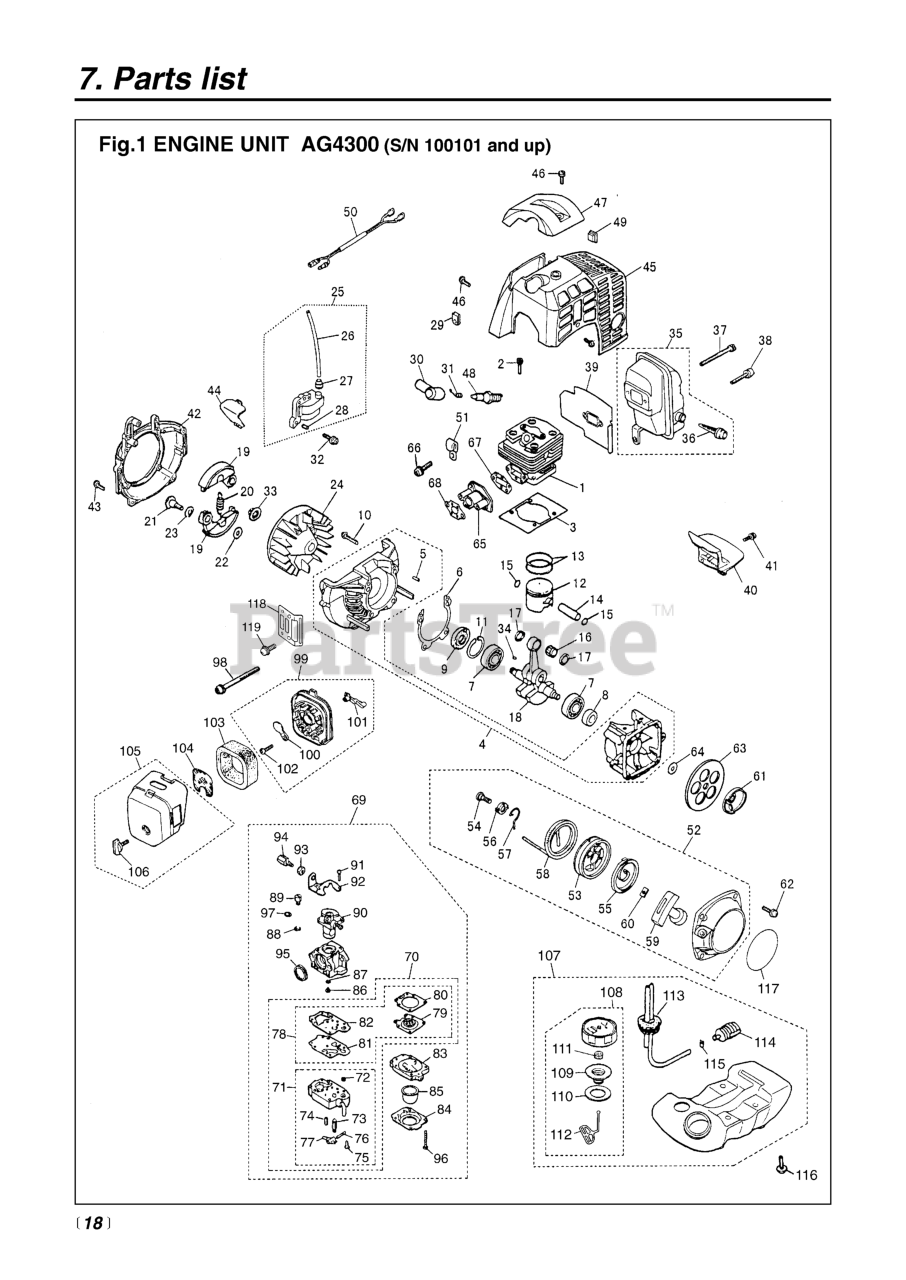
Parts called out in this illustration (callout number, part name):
2	BOLT, M5 X 22
3	GASKET, BASE
4	CRANKCASE COMP (RPLS. -21100)
5	PIN
6	GASKET
8	SEAL
9	SEAL, OIL (RPLS 1200-21220)
10	BOLT, M5 X 30
11	RING, SNAP, M32 x 1.2
13	RING, PISTON (RPLS -41210)
14	PIN, PISTON
15	RING, SNAP
16	BEARING
17	WASHER
18	CRANKSHAFT COMPL
19	SHOE, CLUTCH (RPLS 4500-51110)
20	SPRING
21	SCREW
22	WASHER
23	WASHER (RPLS. -51240)
24	ROTOR
25	COIL ASSEMBLY
26	CORD (RPLS 4700- )
27	CAP
29	GROMMET
30	CAP
31	SPRING
32	BOLT, M4 x 22
34	KEY
35	MUFFLER ASSEMBLY
36	ARRESTER (RPLS 5850-15140)
37	BOLT, M5 x 65
38	BOLT (REPLACES 01252-30514)
39	GASKET, MUFFLER (RPLS -15210)
40	PLATE (RPLS-15220)
41	SCREW,M5 X 14 (RPLS 1400-15510
42	COVER
43	BOLT M5 x 20 (RPLS -12280)
45	COVER
46	SCREW M5 x 12
47	GUARD
50	CORD COMPLETE
51	CLAMP (RPLS 1140-72231)
52	RECOIL ASS
53	REEL
54	SCREW
55	SPRING, SPIRAL
56	COLLAR
57	ARM
58	ROPE (USE 4810-75160)
59	KNOB
60	PLATE, STOPPER
61	PULLEY
62	SCREW, M6 x 14
64	WASHER, M8 x 2.3 (RPLS -20823)
65	INSULATOR (REPLACES -13160)
66	SCREW
67	GASKET, INSULATOR
68	GASKET, CARBURETOR
69	CARBURETOR ASSEMBLY
71	BODY, PUMP
72	SCREEN
73	VALVE
74	SPRING
75	SCREW
76	PIN
77	LEVER
79	DIAPHRAGM
80	GASKET, DIAPHRAGM
81	DIAPHRAGM, PUMP
82	GASKET, PUMP
83	BODY, PURGE
84	COVER, PUMP
85	PUMP, PRIMING
87	RING, O
88	RING
89	SWIVEL
90	VALVE
91	SCREW
93	NUT, CABLE ADJUSTER
94	SCREW, CABLE ADJUSTER
95	RING, PACKING
96	SCREW
97	WASHER
98	SCREW (RPLS 0263-30550)
99	BODY ASSEMBLY
100	PLATE, CHOKE
101	LEVER, CHOKE
102	SCREW (REPLACES 50030272)
103	ELEMENT
104	SCREEN
105	COVER ASSY (REPLACES -82201)
106	KNOB (RPLS -82220)
107	TANK ASSY (RPLS-85003)
108	CAP ASSY (RPLS -85201)
109	HOLDER (REPLACES -85230)
110	PACKING
111	FILTER
112	STOPPER
113	PIPE COMP.
114	FILTER ASSY
115	CLIP (REPLACES 2841-31280)
116	SCREW, M5 X 22
118	GUARD
119	SCREW,M5 X 14 (RPLS 1400-15510
